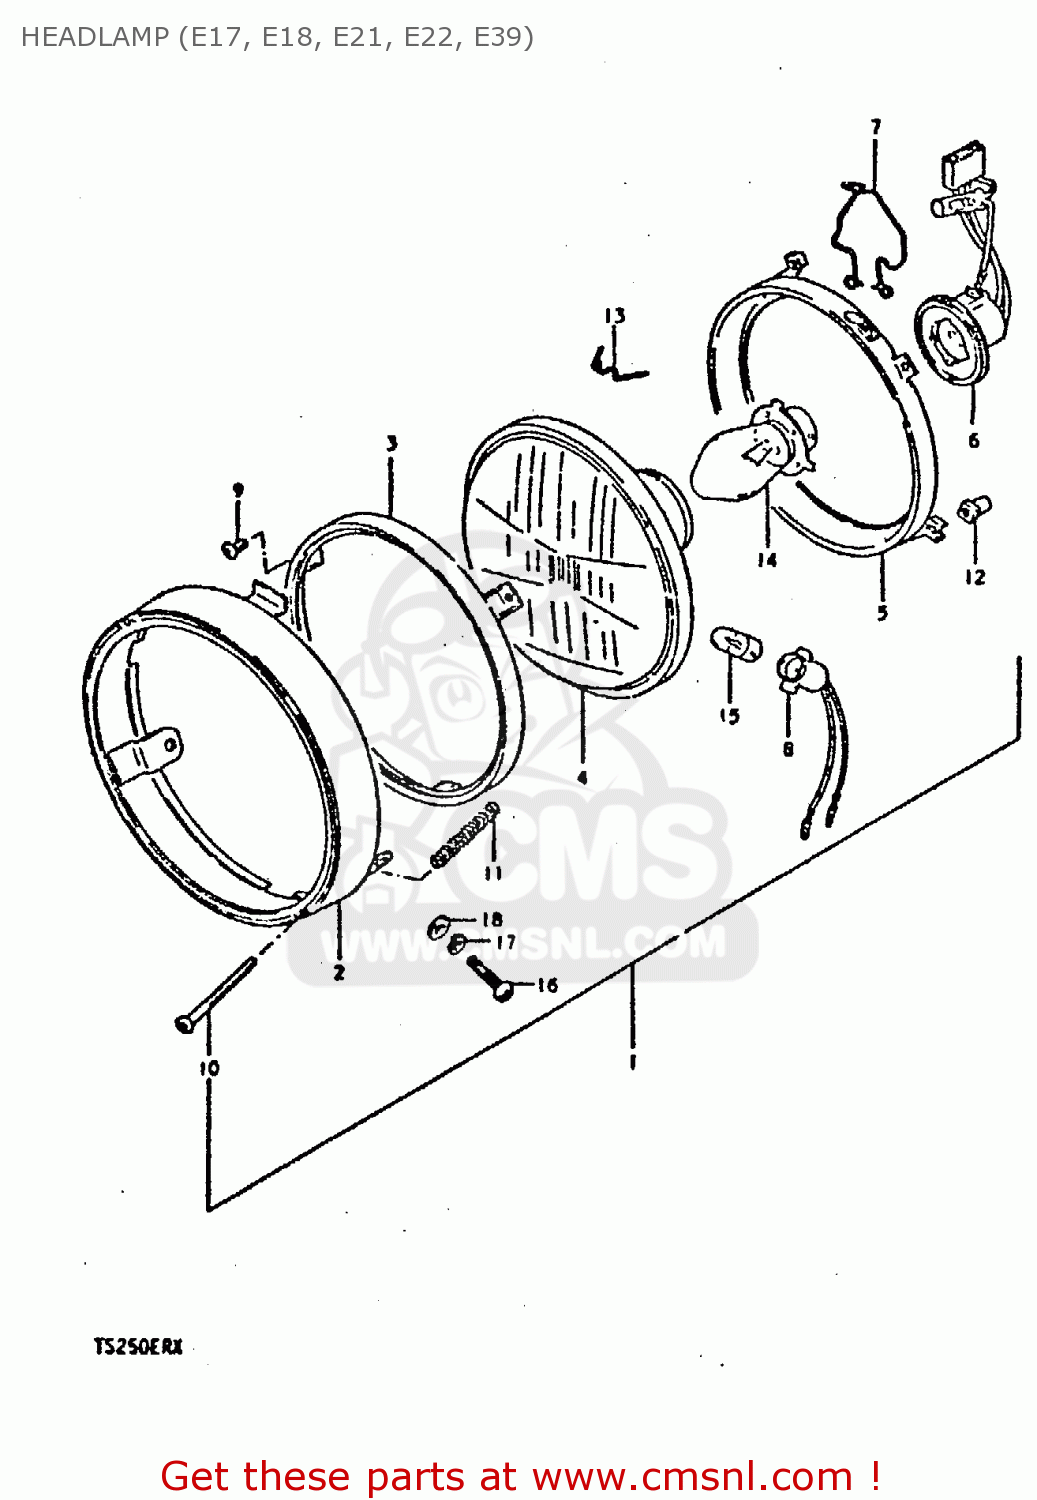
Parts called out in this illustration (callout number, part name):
1	HEADLAMP ASSY
2	RIM
3	RETAINER,HEADLAMP
4	UNIT
5	RING, MOUNTING
6	SOCKET
7	CLAMP,HEADLAMP
8	SOCKET
9	SCREW
10	SCREW,HEADLAMP ADJUST
11	SPRING,ADJUSTING
12	NUT,HEADLAMP ADJUSTER
13	SPRING,HEADLAMP UNIT
14	BULB (6V,25/25W)
15	BULB(6V4W,STANLEY,A1364J)
16	SCREW
17	LOCK WASHER
18	WASHER
